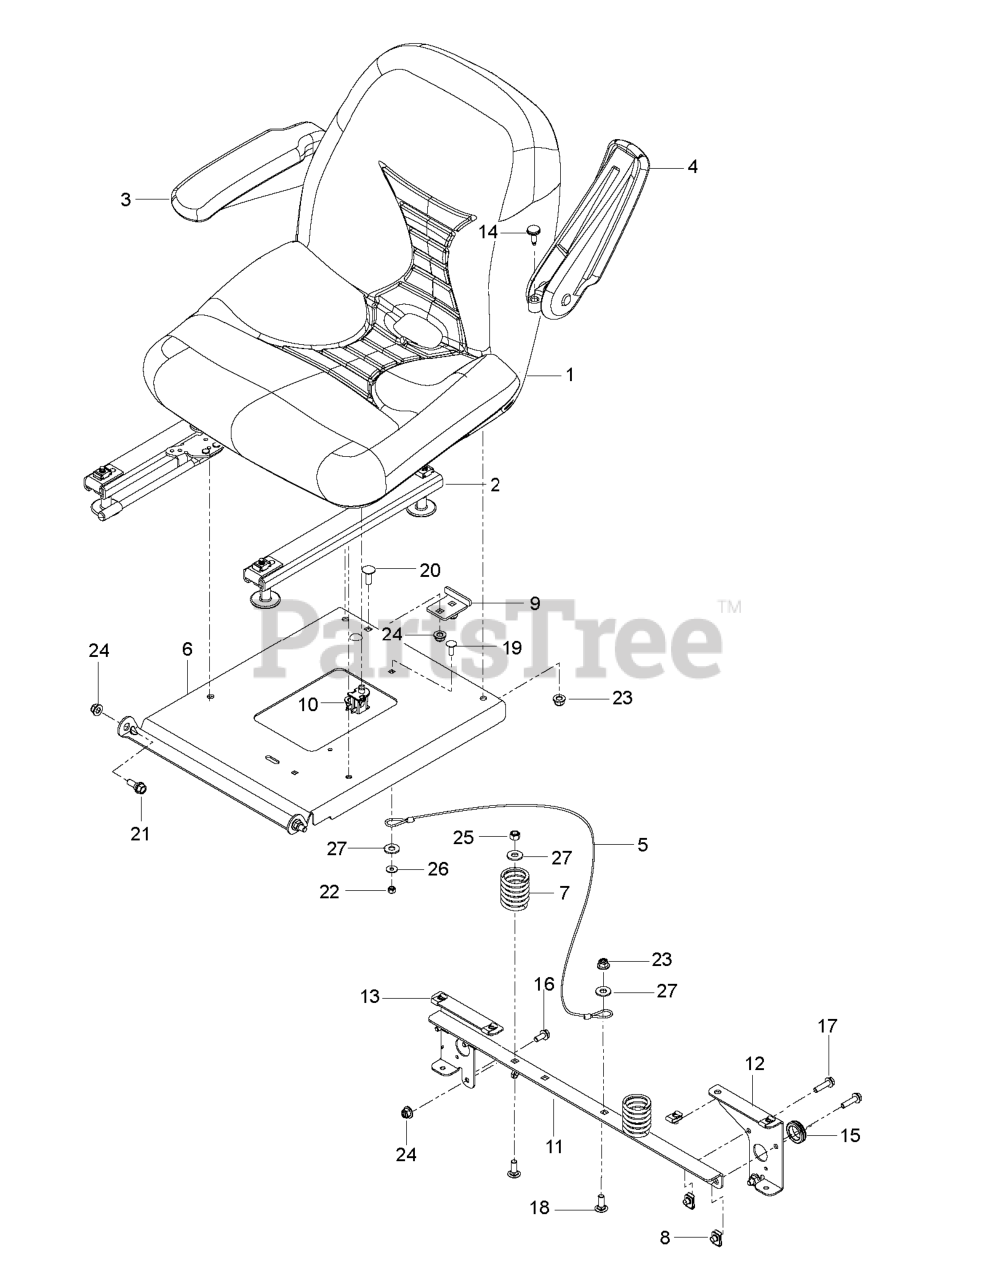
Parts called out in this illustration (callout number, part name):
1	SEAT
2	TRACK ADJUSTMENT KIT
3	ARMREST KIT, RT SQUARE END
4	ARMREST KIT, LT SQUARE END
5	SEAT LANYARD
6	SUPPORT.PNT.SEAT.ORANGE
7	SPRING COMPRESSION
8	U-CLIP 5/16-18 NUT RETAINER
9	STOP, SEAT - BLACK
10	SWITCH.SNAPMOUNT.NC
11	SUPPORT.SEAT. BLK
12	SUPPORT.RT.BLK
13	SUPPORT.LT.BLK
14	ADJUSTER KNOB
15	RUBBER GROMMET
16	HHFS 5/16-18 X 3/4
17	HHFS 5/16-18 X 1.25 TPBLT GD 5
18	BOLT D
19	BOLT
20	RHSNB 5/16-18 X 3/4 GR5 BLK ZN
21	SB 5/16-18 HEX HD GD5, BLK ZN
22	LOCKNUT.NYLOC.1/4-20
23	NUT 3/8-16 HEX FLG NYLOC ZD
24	5/16-18 NYLOC FLANGE NUT
25	NUT
27	RP WASHER 3/8 FLAT
